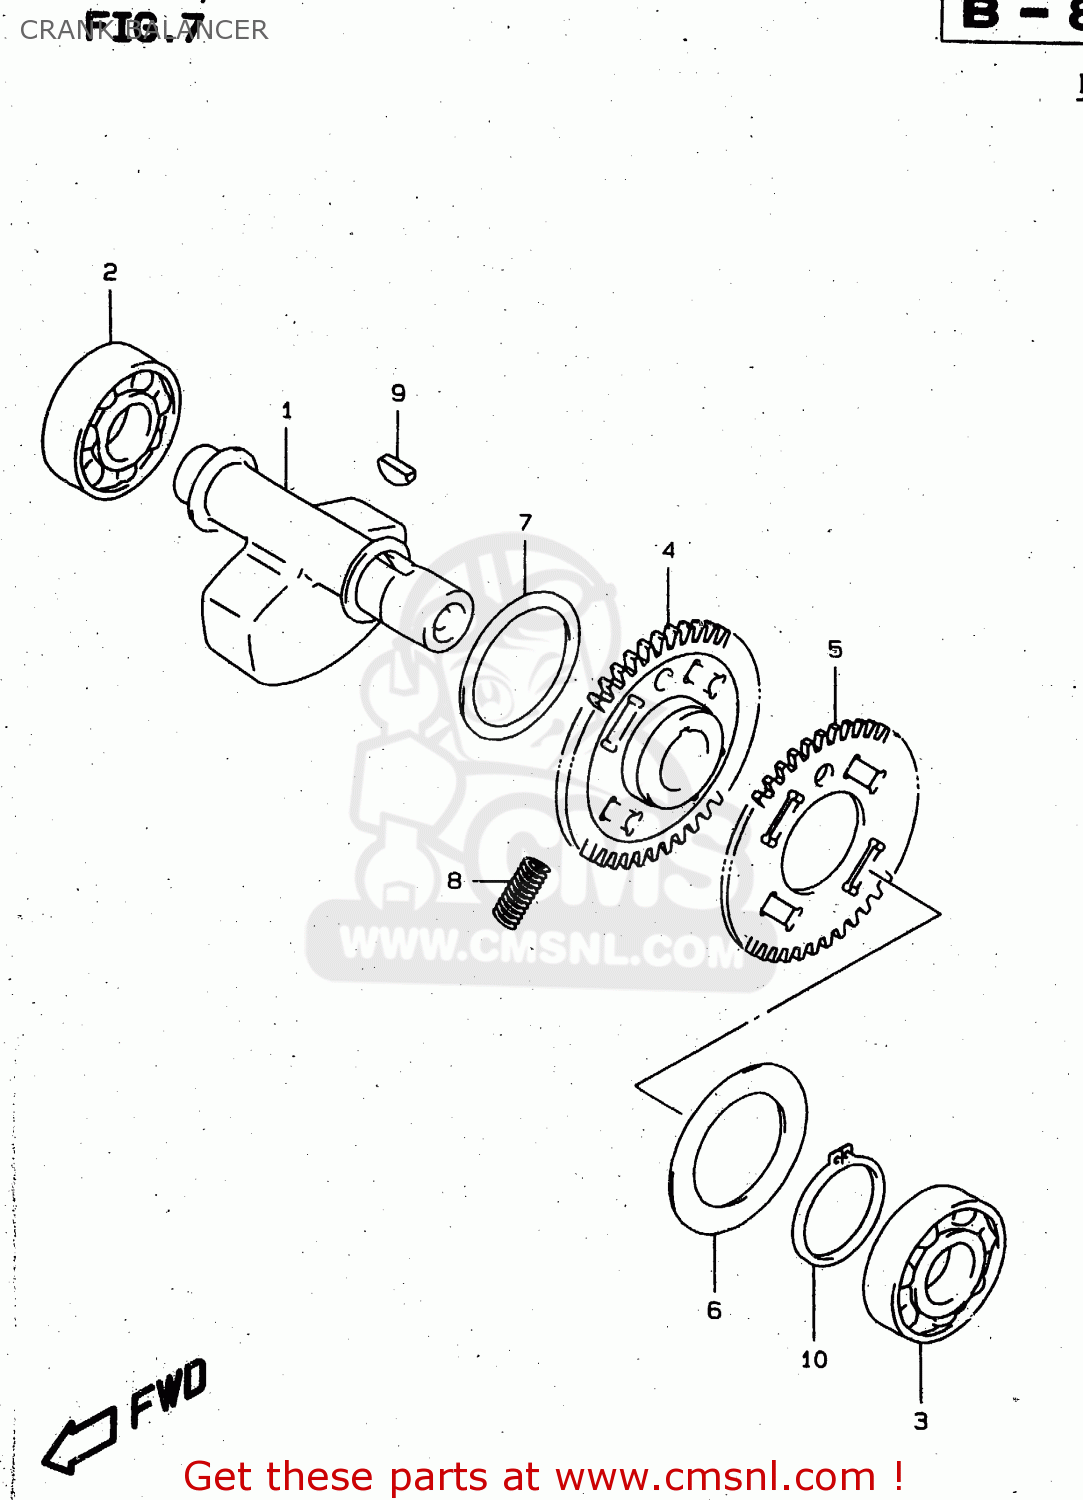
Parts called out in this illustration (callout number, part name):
1	BALANCER,CRANK
2	BEARING(22X56X16)
3	BEARING(20X47X14)
4	GEAR,CRANK BALANCER DRIVE
5	GEAR,CRANK BALANCER DRIVE
6	WASHER
7	WASHER
8	SPRING
9	KEY
10	CIRCLIP
